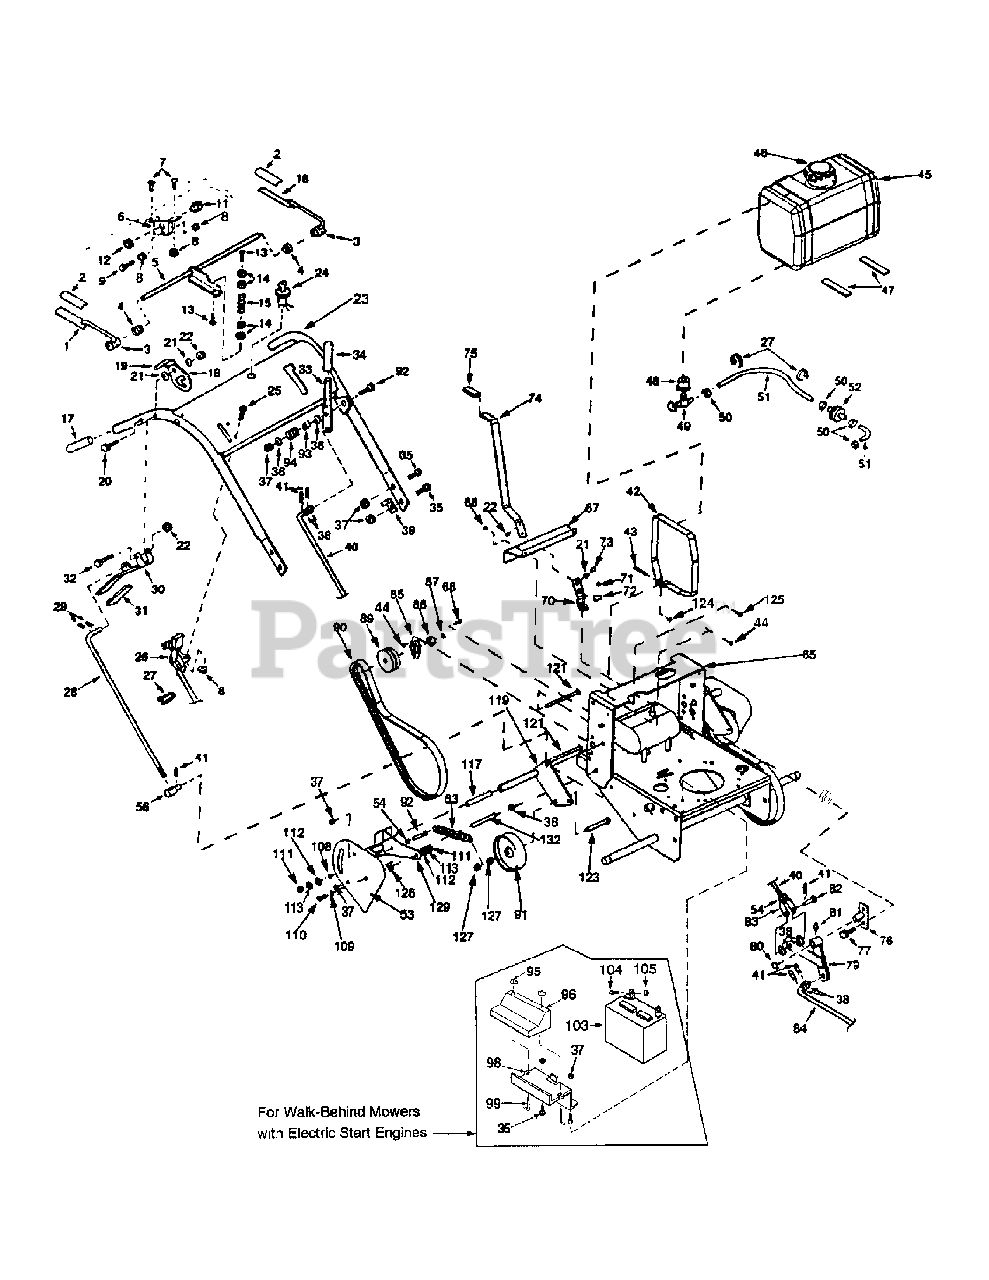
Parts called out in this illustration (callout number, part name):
1	Right Handle, Operator Presence
2	Grip, 3-1/2" Yellow
3	Set Screw, 1/4-20 x 3/8 Square Hd.
4	Bushing, Nylon
5	Shaft Assembly
6	Switch Mount
7	Machine Screw, #10-32 x 5/8 Truss Hd.
8	Hex Nut, #10-32 Nylock
9	Cap Screw, #10-32 x 1-1/2 Socket Hd.
11	Switch, Operator Presence
12	Hex Nut, Machined
13	Machine Screw, #5-40 x 1/2 Round Hd.
14	Hex Nut, #5-40
15	Return Spring
16	Left Handle, Operator Presence
17	Grip, 4-1/2" Black
18	Lever, Neutral Latch, R.H.
18	Lever, Neutral Latch, L.H.
19	Grip, 1-1/4" Black
20	Cap Screw, 5/16-18 x 2 Hex Hd.
21	Flat Washer, 5/16
22	Hex Nut, 5/16-18 Nylock
23	Handle Assembly
24	Ignition Switch
24	Hex Nut, 5/8-32 with Cap
25	Machine Screw, #10-32 x 1/2 Hex Washer Hd.
26	Engine Throttle, 13 HP Kohler
26	Engine Throttle, 14 HP Kawasaki
26	Engine Throttle, 16 HP B & S
26	Engine Throttle, 17.0 HP Engine
27	Cable Ties, Black
28	Control Rod, Steering/Brake
29	Cotter Pin, 3/32 x 3/4
30	Steering/Brake Lever
31	Grip, 4-1/2" Black
32	Cap Screw, 5/16-18 x 2-1/4 Hex Hd.
33	Lever, Blade Clutch
34	Grip, 5" Black
35	Cap Screw, 3/8-16 x 1-1/4 Hex Hd.
36	Flat Washer, 3/8 Large
37	Hex Nut, 3/8-16 Nylock
38	Flat Washer, 3/8 Small
39	Support Clamp, 1/2"
40	Upper Rod, Blade Clutch
41	Hairpin, 3/8" - 1/2"
42	Tank Strap
43	Machine Screw, 1/4-20 x 2-1/2 Phillips Hd.
44	Hex Nut, 1/4-20
45	Gas Tank, 5 Gallon
46	Cap, Gas Tank
47	Rubber Pad
48	Rubber Bushing
49	Fuel Valve
50	Uni-Clamp
51	Hose, 1/4 Fuel Line
52	Fuel Filter
53	Belt Guard
54	Hex Nut, 3/8-16
56	Swivel Joint
63	Spring, Idler Tension
65	Engine Deck, 32" Mower
67	Shift Panel
68	Carriage Bolt, 1/4-20 x 3/4
70	Shift Arm
71	Hex Nut, 3/8-24 Nylock
72	Washer, Belleville, 1.12 x .38 x .053
73	Cap Screw, 5/16-18 x 3/4 Hex Hd.
74	Shift Handle
75	Grip, 3-1/2" Yellow
76	Bellcrank Pivot
77	Carriage Bolt, 1/4-20 x 1’’
79	Clutch Bellcrank
80	E-Ring, 5/8"
81	Grease Fitting, 1/4-28 Straight
82	Clevis Pin, 3/8 x 1-3/16
83	Yoke, 3/8-16 Female
84	Rod, Blade Clutch
85	Bearing Housing
86	Bearing
87	Retaining Ring, External
89	Pulley, Jackshaft
90	Drive Belt
91	Drive Idler
92	Cap Screw, 3/8-16 x 2 Hex Hd.
93	Spring Sleeve
94	Spring
95	Wing Nut
96	Battery Cover
98	Gray Battery Tray
99	Battery Hold Down Rod
103	Battery, 12 Volt
104	Cap Screw, 1.4-20 x 3/4 Hex Hd.
105	Hex Nut, 1/4-20 Nylock
108	Roller Tube
109	Lock Washer, 3/8
110	Hex Head Cap Screw 3/8 - 16 x 1"
111	Shoulder Nut
112	Washer, Slide
113	Washer, Spec 1/2
117	Sleeve Idler
119	Idler Bracket, R.H.
119	Idler Bracket, L.H.
121	Carriage Bolt, 3/8-16 x 5-1/2
123	Hex Cap Screw, 1/2-13 x 3-1/2
124	Hex Nut, 1/4-20
125	Carriage Bolt, 1/4-20 x 3/4
127	Nylock Nut, 1/2 - 13
128	(Purchase Locally)
129	Spring Tension Adj.
132	Tube Spacer
